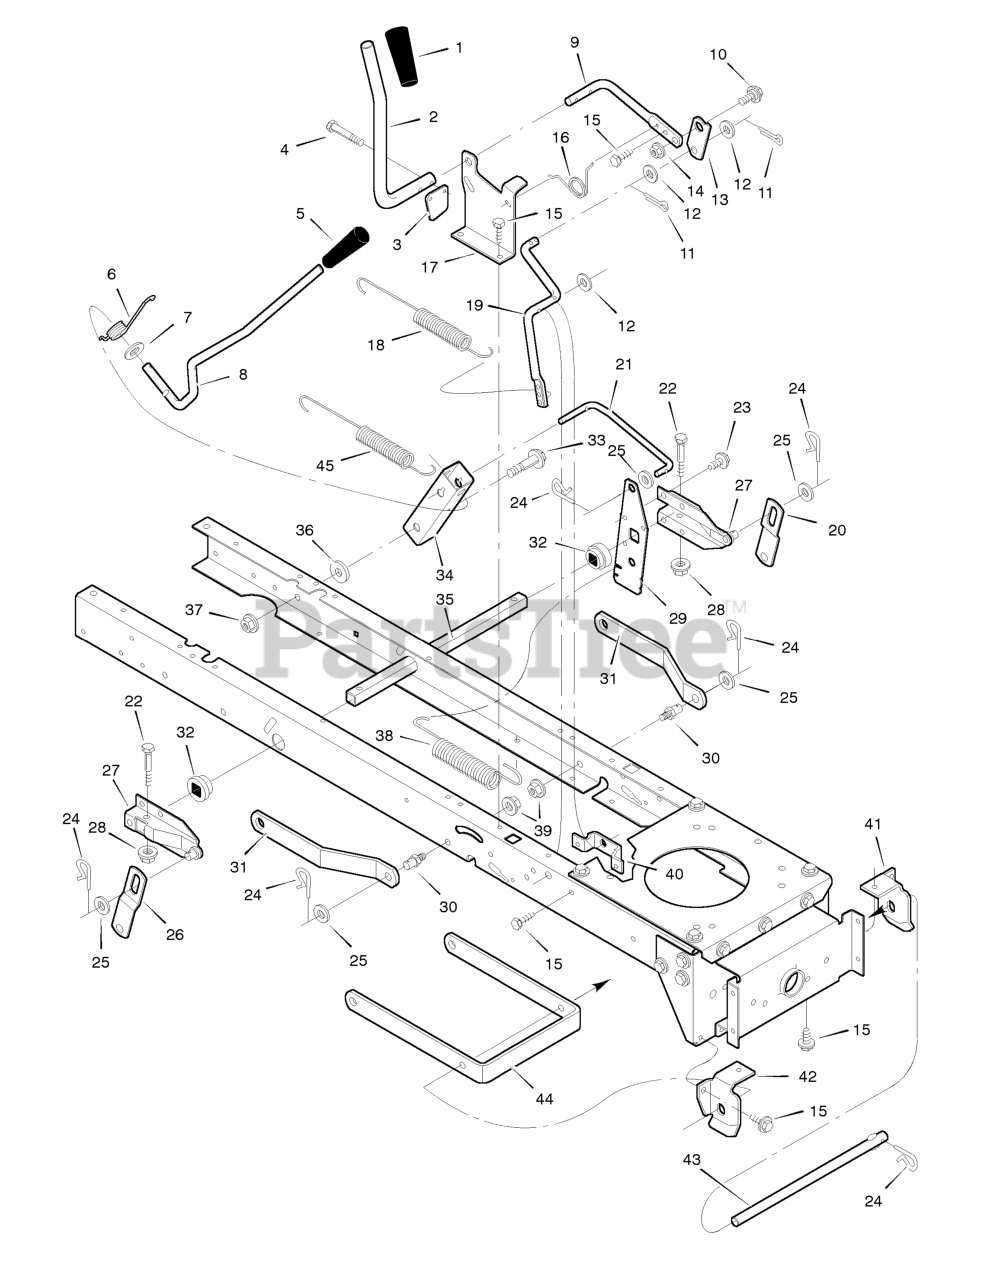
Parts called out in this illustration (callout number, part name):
1	Grip
2	Handle, PTO
3	Pad, Switch
4	Screw, Hex
5	Grip
8	Lever, Lift
9	Lever, PTO
10	Bolt, Shoulder
11	Pin, Cotter
13	Link, PTO
14	Nut, Flange
17	Bracket, PTO
18	Spring, Blade Drive
19	Crank, PTO
20	Link, Left Lift
21	Link, Lift
24	Pin, Hair
26	Link, Right Lift
27	Lever Assembly, Lift
28	Nut, Flange
29	Plate, Lift Arm
30	Pin
31	Bracket, Rear Suspension
32	Bushing
33	Bolt, Shoulder
34	Bracket, Pivot
35	Tube, Deck Lift
37	Nut, Flange
39	Nut, Flange
40	Bracket, PTO
41	Hanger, Left Deck
42	Hanger, Right Deck
43	Rod, Hanger
44	Bracket, Suspension
